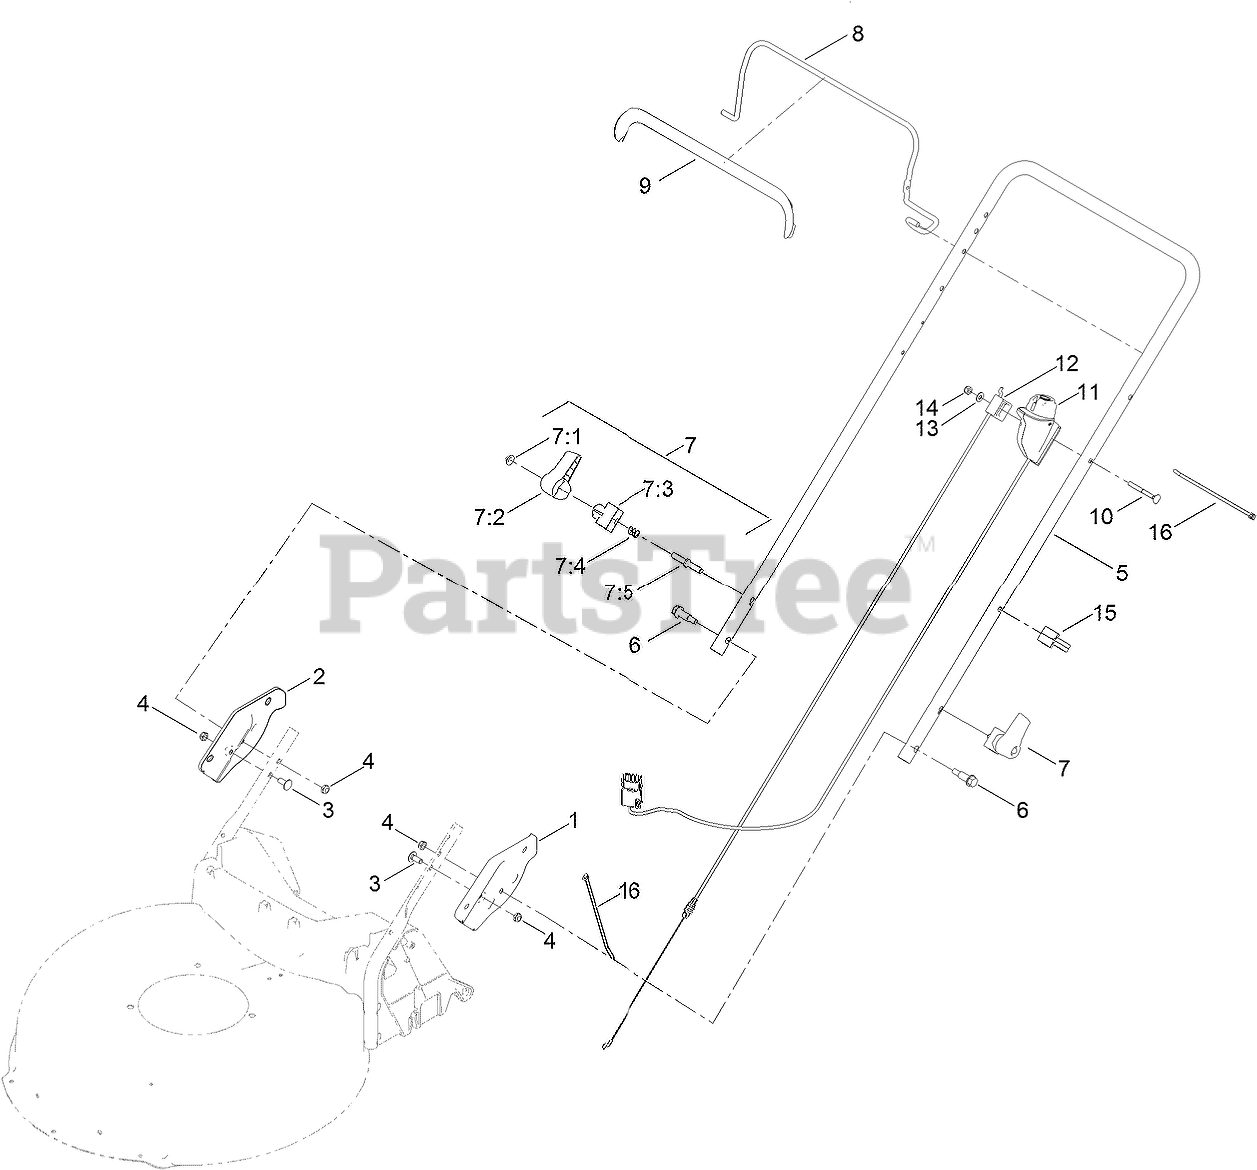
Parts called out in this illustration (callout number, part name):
1	PLATE-HANDLE, WELDMENT LH
2	PLATE-HANDLE, WELDMENT RH
3	BOLT-CARR
4	NUT-HEX
6	BOLT-SHOULDER
6	BOLT-SHOULDER, HHF
7	QUICK RELEASE ASM
7:1	NUT-PUSH
7:2	LEVER-RELEASE
7:3	ANCHOR-SPRING
7:4	SPRING-COMPRESSION
7:5	ROD-RELEASE
8	BAIL-BRAKE
9	COVER-BAIL
10	SCREW-HANDLE
11	STARTER SWITCH ASM
12	CABLE-BRAKE, HP
13	WASHER-FLAT
14	NUT-LOCK, NI
15	GUIDE-CABLE
16	TIE-CABLE
